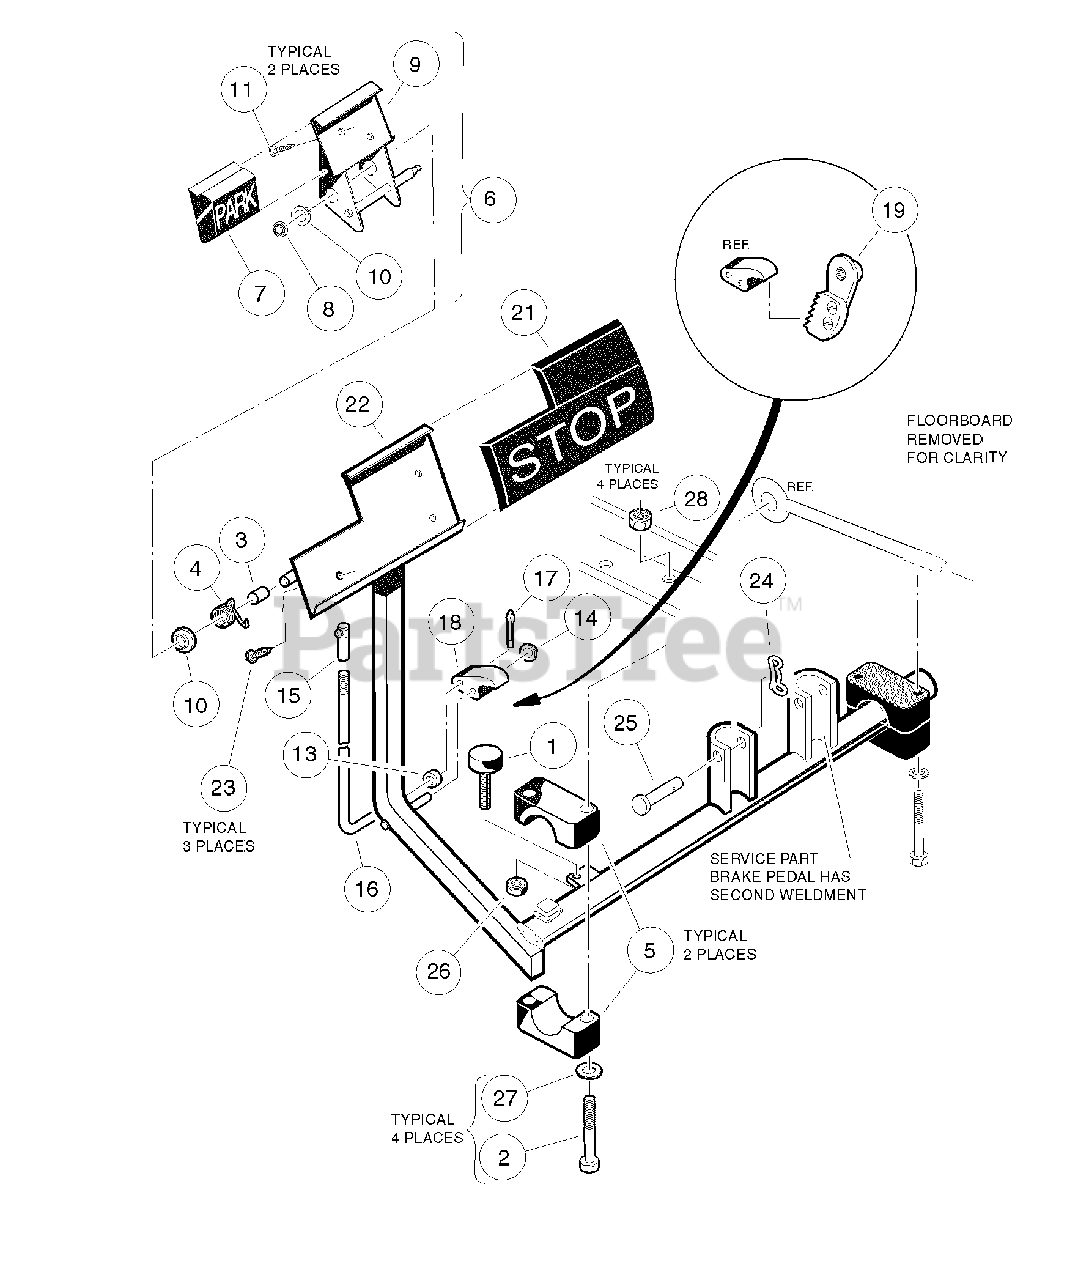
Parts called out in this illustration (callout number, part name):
1	Bumper, Rubber
2	Screw, 5/16-18 X 2.50 Hex Cap
3	Hill Brake Spacer
4	Spring, Hill Brake Torsion
5	Package, Brake Mounting Block
6	Kit, Hill Brake Pedal
7	Pad, Hill Brake
8	Pushnut, 3/8
9	Hill Brake Weld Assembly
10	Bushing, Nylon
11	Screw, #10-16 Type AB, Sheet Metal
12	Kit, Hill Brake Latch
13	Sleeve, Hill Brake Rod
14	Pushnut, 3/8
15	Ball Joint, 1/4-28
16	Rod, Hill Brake
17	Pin, Cotter, 7/64 x 1/2 Stainless-Steel
18	Pawl, Hill Brake
19	Ratchet Assembly
20	Brake Pedal Kit
21	Pad, Brake Pedal
22	Weldment, Brake Pedal 4wb Std
23	Screw, #10-16 Type AB, Sheet Metal
24	Pin, Bow Tie Locking
25	Pin, 3/8 X 1-5/16 Clevis
26	Nut, 1/4-20 Hex
27	Washer, 5/16 Type A Flat
28	Locknut, 5/16-18 Nylon Insert
